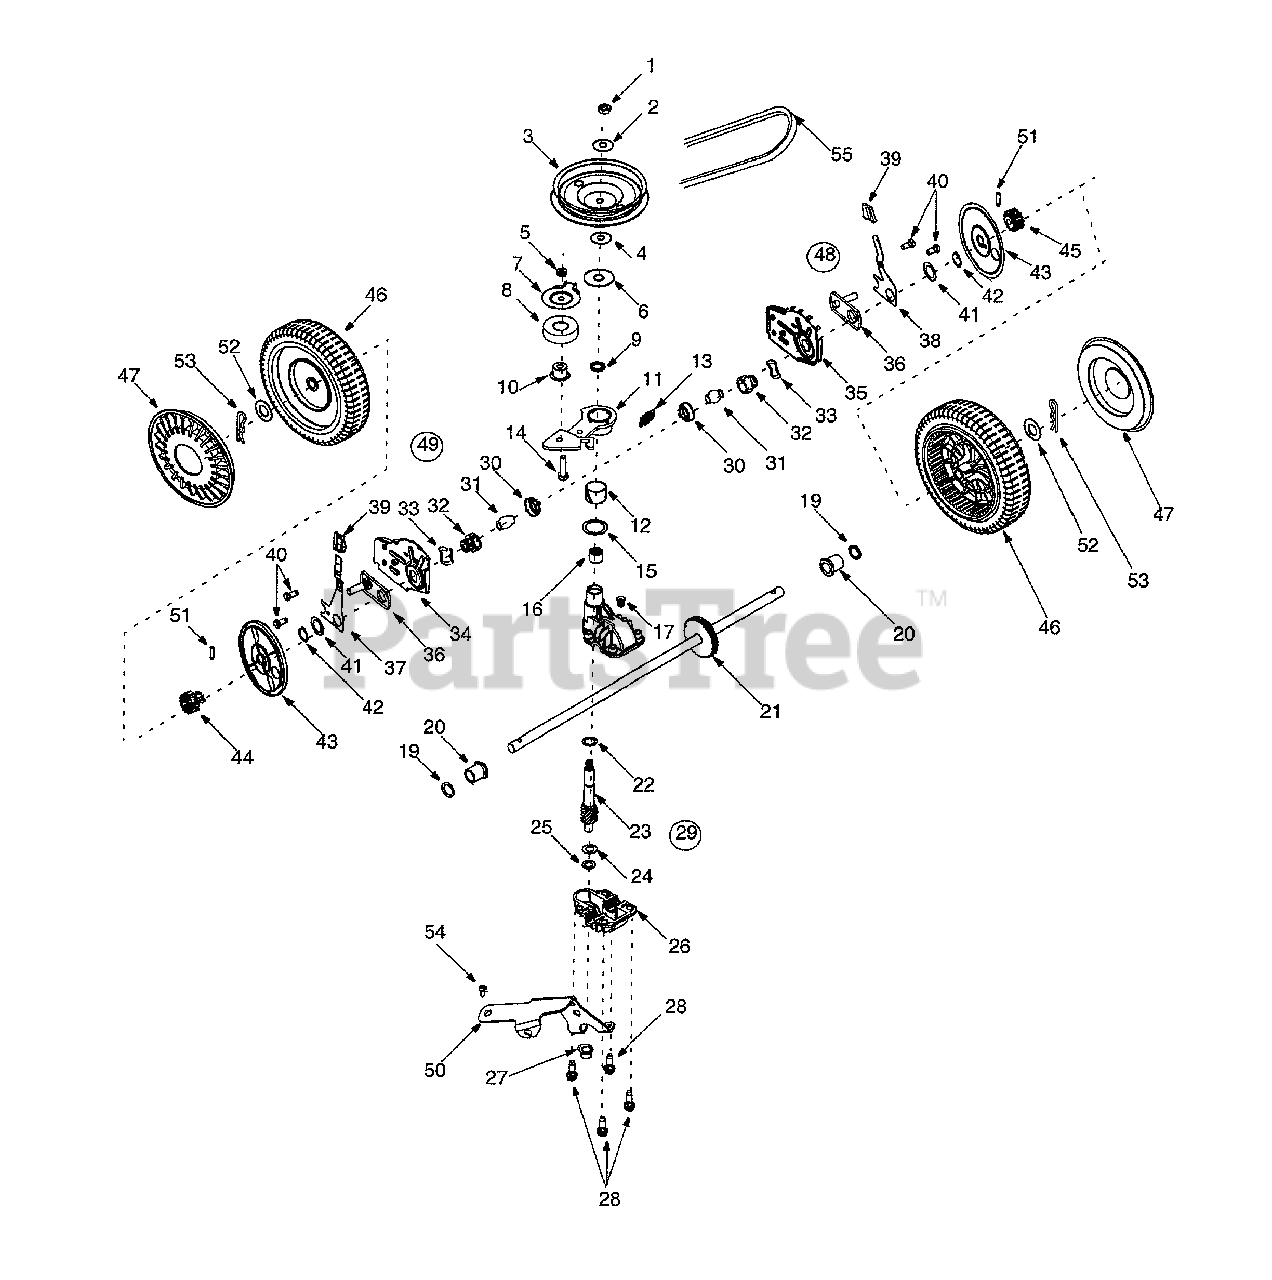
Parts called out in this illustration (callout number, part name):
1	Hex Jam Nut 5/16-24
2	Bell Washer .325 x .930 x .045
3	Pulley, 3.82 x .313 x .68
4	Bell Washer .325 x .930 x .045
5	Lock Nut 1/4-28
6	Flat Washer .442 x 1.38 x .060
7	Belt Keeper
8	Ball Bearing
9	Oil Seal
10	Flange Spacer
11	Idler Bracket Assembly
12	Bearing Sleeve
13	Extension Spring
14	Hex Cap Screw 1/4-28 x 1.00
15	Flat Washer .865 x 1.145 x .030
16	Needle Bearing .438 x .625 x .500
17	Plug 1/4 x .437
19	Oil Seal .500 x .687 x .094
20	Flange Bearing
21	Output Shaft
22	Flat Washer .504 x .700 x .030
23	Pinion Shaft 10T
24	Thrust Washer .375 x .70 x .030
25	Thrust Washer .388 x .625 x .062
26	Lower Housing
27	Flange Bearing .378 x .531 x .370
28	Hex Screw w/Washer 1/4-20 x .750
29	Transmission Assembly
30	Bearing Retainer
31	Bearing Sleeve .50 I.D.
32	Bearing Support
33	Wave Washer 1.5 x 1.0 x .029
37	RH Front Lever
38	LH Front Lever
39	Knob
40	Hex Cap Screw 3/8-16 x .75
41	Washer DD 1.5" O.D.
42	Snap Ring
43	Wheel Dust Cap
44	Gear 14T RH
45	Gear 14T LH
46	Wheel, 8x2 Grey
47	Hubcap: Euro Gray
48	RH Height Adj.
49	LH Height Adj.
50	Cable Idler Bracket
51	Dowel Pin
52	Flat Washer 1/2 x 1.00 x .063
53	Cotter Pin .08 x 1.42
54	Screw
55	Belt
